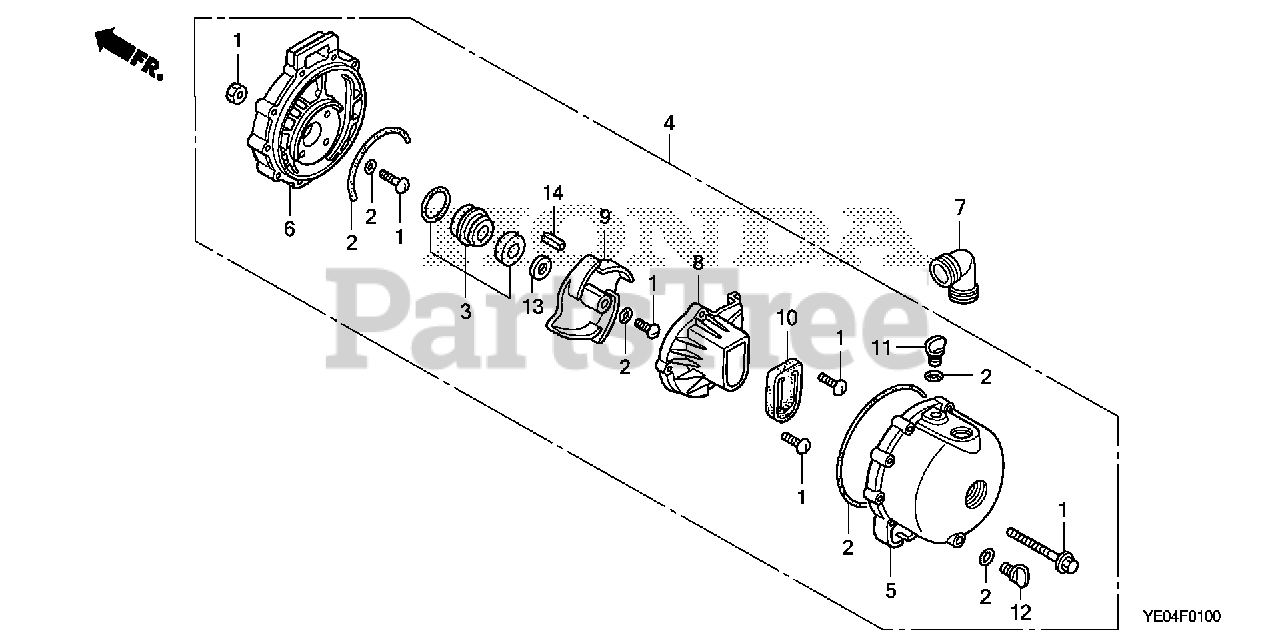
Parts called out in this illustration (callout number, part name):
1	HARDWARE SET
2	O-RING SET
3	SEAL SET, MECHANICAL
4	PUMP ASSY. (TO ORDER COMPONENTS, SEE SECTION F-2.)
5	PUMP ASSY. (TO ORDER COMPONENTS, SEE SECTION F-2.)
6	PUMP ASSY. (TO ORDER COMPONENTS, SEE SECTION F-2.)
8	PUMP ASSY. (TO ORDER COMPONENTS, SEE SECTION F-2.)
10	VALVE, CHECK
11	CAP, FILLER
12	PLUG, DRAIN
13	SHIM A, IMPELLER (0.006")
13	SHIM B, IMPELLER (0.015")
13	SHIM C, IMPELLER (0.030")
